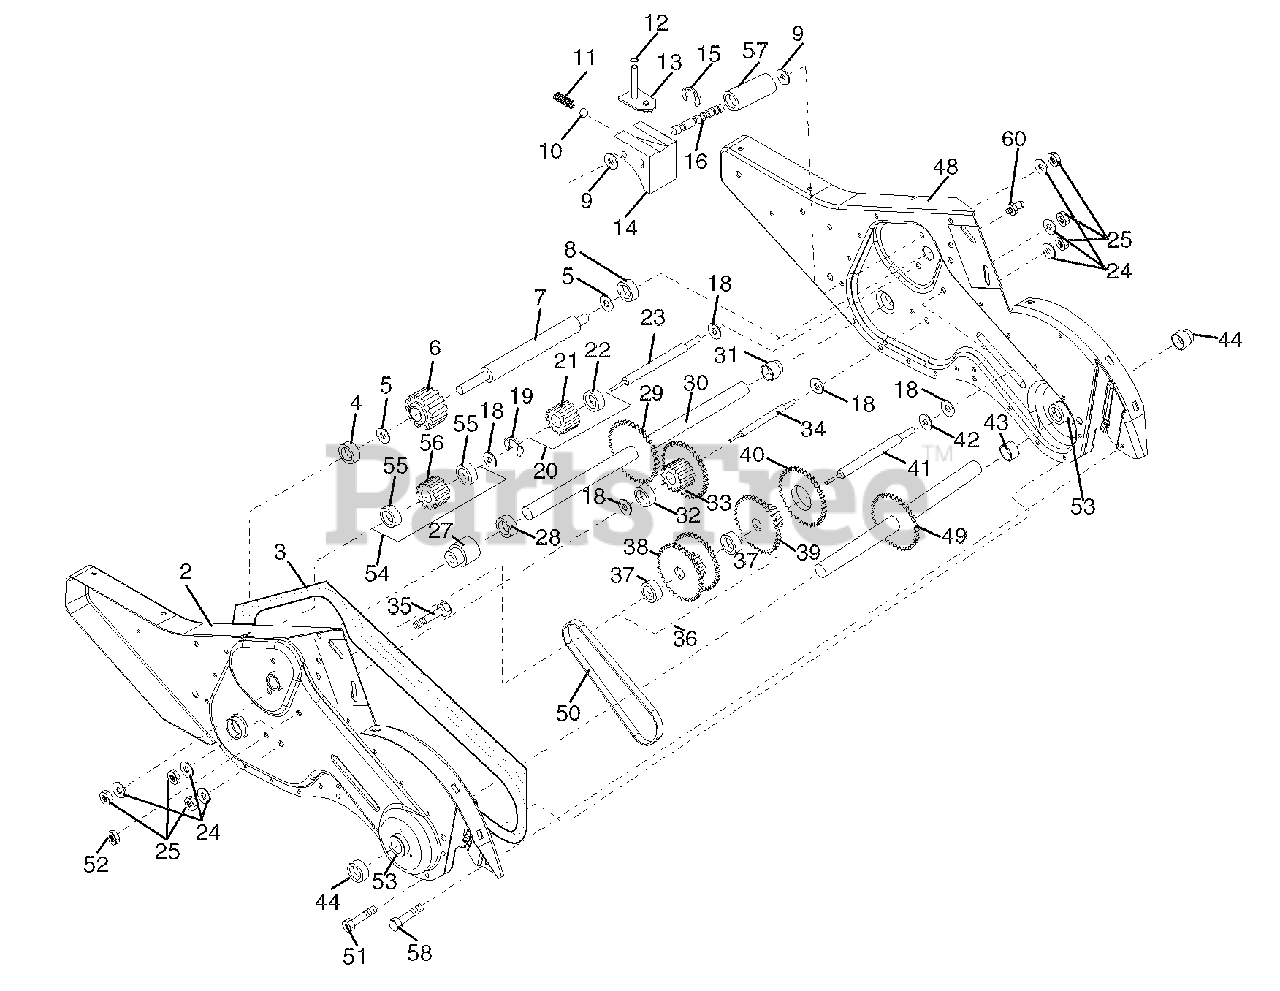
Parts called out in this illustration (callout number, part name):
1	Transmission Assembly
2	Gearcase, L.H. w/Bearing
3	Gasket, Gearcase
4	Bearing, Needle
5	Washer, Thrust 5/8 x 1.10 x 1/32
6	Pinion, Input
7	Shaft, Input
8	Bearing, Needle
9	Washer, Seal
10	Ball, Steel
11	Spring, Shift, Fork
13	Arm, Shift
14	Fork, Shift
15	Ring, Klip
16	Shaft, Shift
19	Ring, Klip
20	Gear, Assembly, Reverse Idler
21	Gear, Reverse Idler
22	Bearing, Needle
23	Shaft, Reverse Idler
24	Washer, Lock 7/16
25	Nut, Hex 7/16-20
27	Bearing, Shaft, Ground Drive L.H.
28	Spacer 0.765 x 1.125 x 1.23
29	Chain #35-50 Pitch
30	Ground Shaft Assembly
31	Bearing, Shaft, Ground Drive R.H.
32	Spacer 0.70 x 1.00 x 1.150
33	Sprocket and Gear Assembly
34	Shaft, Reduction
35	Screw, Whiz, Lock 5/16-18 x 3-1/2
36	Sprocket Assembly w/Bearing
37	Bearing, Needle
38	Sprocket, Tine
39	Gear, Cluster, Red 1st & 2nd
40	Gear, Reverse
41	Shaft, Reduction
42	Washer, Thrust
43	Spacer 1.01 x 1.75 x 0.760
44	Seal Asm. OIl
48	Gearcase, R.H. w/Bearing
49	Shaft, Tine
50	Chain, Roller #50-50 Pitch
51	Screw 1/4-20 x 1/2
52	Nut, Hex 5/16-18
53	Bearing Kit, Tine Shaft
54	Gear, DRT Idler w/Bearing
55	Bearing, Needle
56	Gear, DRT Idler
57	Spacer, Split .52 x .64 x 1.04
58	Screw 1/4-20 x .875
60	Fitting Grease
